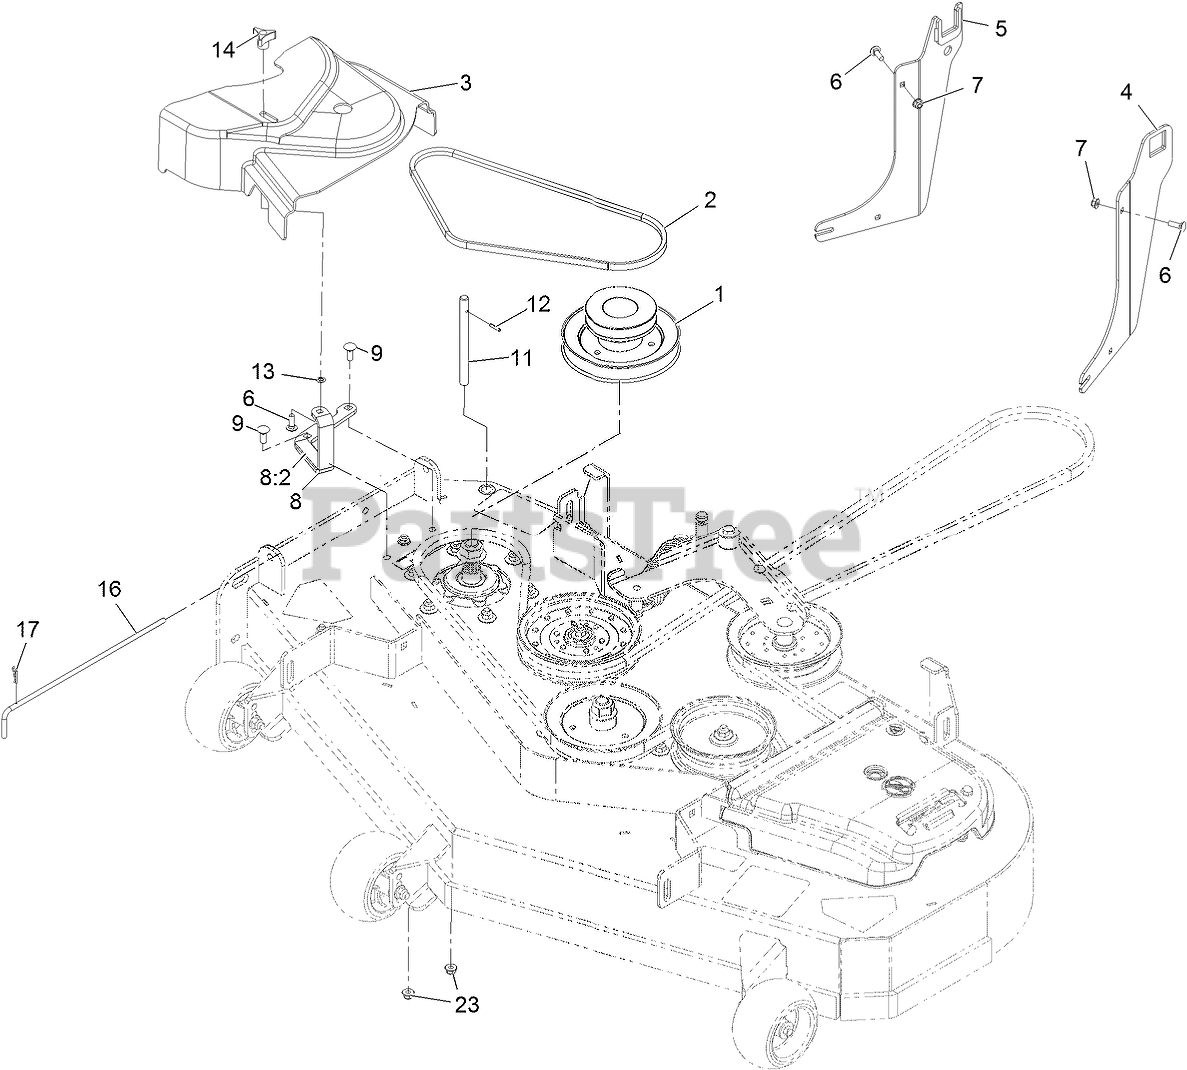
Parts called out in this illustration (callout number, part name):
1	JACKSHAFT-UV DRIVE 48 SPL
2	BELT-UV E 48
3	COVER-BELT, UV 48
4	BRACKET ASM, LH
5	BRACKET ASM, RH
6	BOLT-CARR
7	NUT-HF, NI
8	ASM-CVR BRKT W/DECAL
8:2	DECAL-DANGER
9	BOLT-CARR
11	SHAFT-CATCHER, GRASS
12	PIN-ROLL
13	RING-RETAINING, BOLT
14	KNOB-3 PRONG
16	PIN,CHUTE PIVOT
17	PIN-COTTER
23	Nut-Nyloc 3/8-16 Flg
